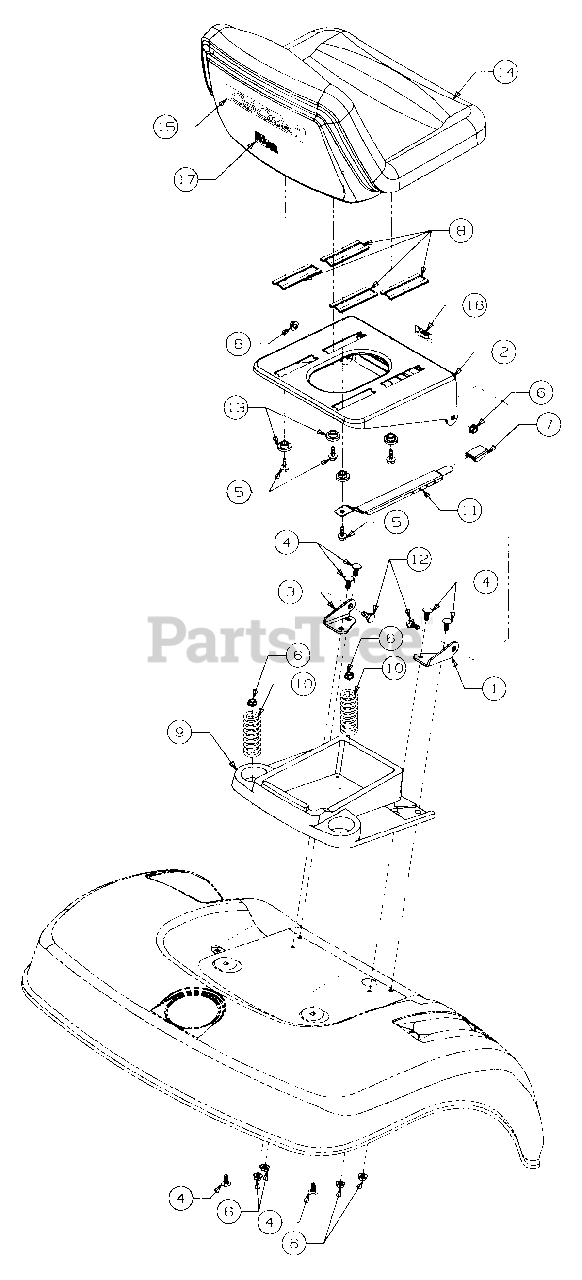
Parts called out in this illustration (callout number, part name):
5	Screw, Hex Wash Sf-Tapp , 5/16-18 x .75 Lg
6	Nut, Hex Flange Top Lock, 5/16-18
7	Knob, Seat Adjuster
8	Slide, Seat
9	Tray, Tool
10	Spring, Compression, 1.9 OD x 2.4 Lg
11	Adjuster, Seat
12	Bolt, Shoulder
13	Spacer, Shoulder
14	Seat, High Back
15	Graphic, Seat Back Script
16	Graphic, Seat Adjuster
17	Graphic, Made in USA.
